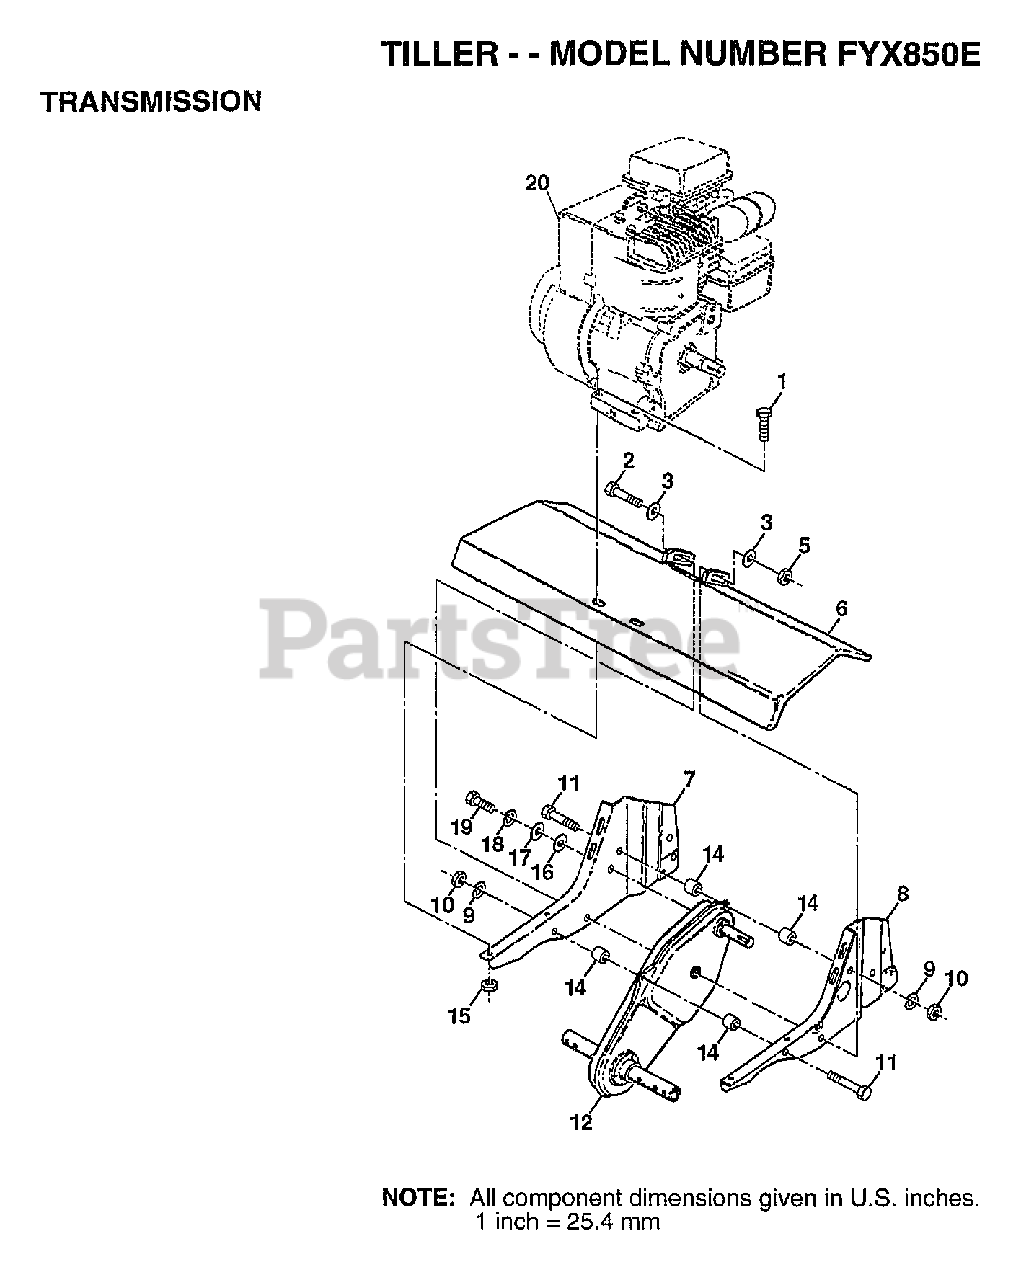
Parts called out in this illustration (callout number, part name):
1	BOLT.HEX.5/16-1.5
2	BOLT HEX 3/8-16
3	WASHER
5	NUT
6	TINE SHIELD
7	BRACKET.ENGINE.RH
8	ENGINE BRKT LH TI
9	LOCKWASHER
10	NUT.HEX.5/16-18
14	SPLIT SPACER RT
16	WASHER
17	WASHER
18	LOCKWASHER
19	BOLT
